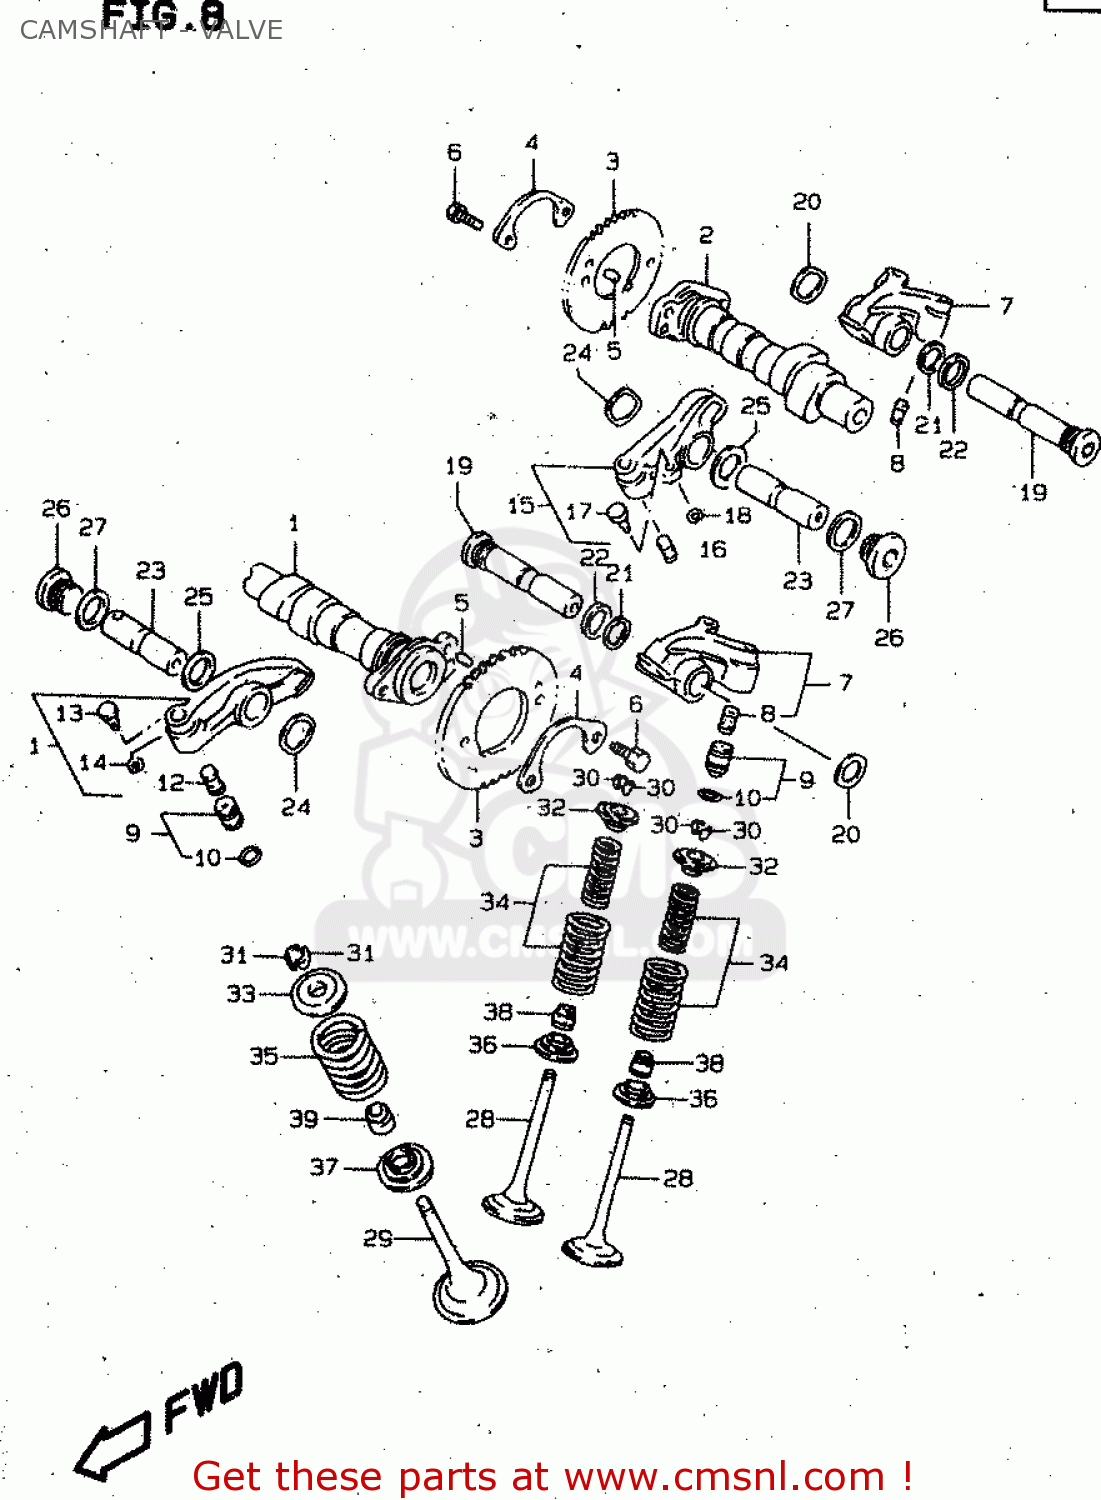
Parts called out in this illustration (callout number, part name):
1	CAMSHAFT,FR
2	CAMSHAFT,RR
3	SPROCKET,CAMSHAFT
4	WASHER,CAM CHAIN SPROCKET
5	PIN
6	BOLT(6X12.5)
7	ARM,VALVE ROCKER INTAKE
8	CHAMBER,VALVE LASH ADJUSTER
9	ADJUSTER,HYDRAULIC VALVE
10	O-RING,ADJUSTER
11	ARM,VALVE ROCKER FR EXHAUST
12	CHAMBER,VALVE LASH ADJUSTER
13	PIN,DECOMP
14	E RING
15	ARM,VALVE ROCKER RR EXHAUST
16	CHAMBER,VALVE LASH ADJUSTER
17	PIN,DECOMP
18	E RING
19	SHAFT,INTAKE VALVE ROCKER ARM
20	WASHER
21	WASHER
22	GASKET(16X22X2) (NAS)
23	SHAFT,EXHAUST VALVE ROCKER ARM
24	WASHER
25	WASHER(16X26X1)
26	PLUG,18X11
27	GASKET(18X24.2X2) (NAS)
28	VALVE,INTAKE
29	VALVE,EXHAUST
30	COTTER,VALVE
31	COTTER,VALVE
32	RETAINER,VALVE SPRING
33	RETAINER,VALVE SPRING
34	SPRING SET,VALVE
35	SPRING,VALVE OUTER
36	SEAT,VALVE SPRING
37	SEAT,VALVE SPRING
38	SEAL,OIL(5.5X11X8.2)
39	SEAL,OIL(7X14.4X9)
